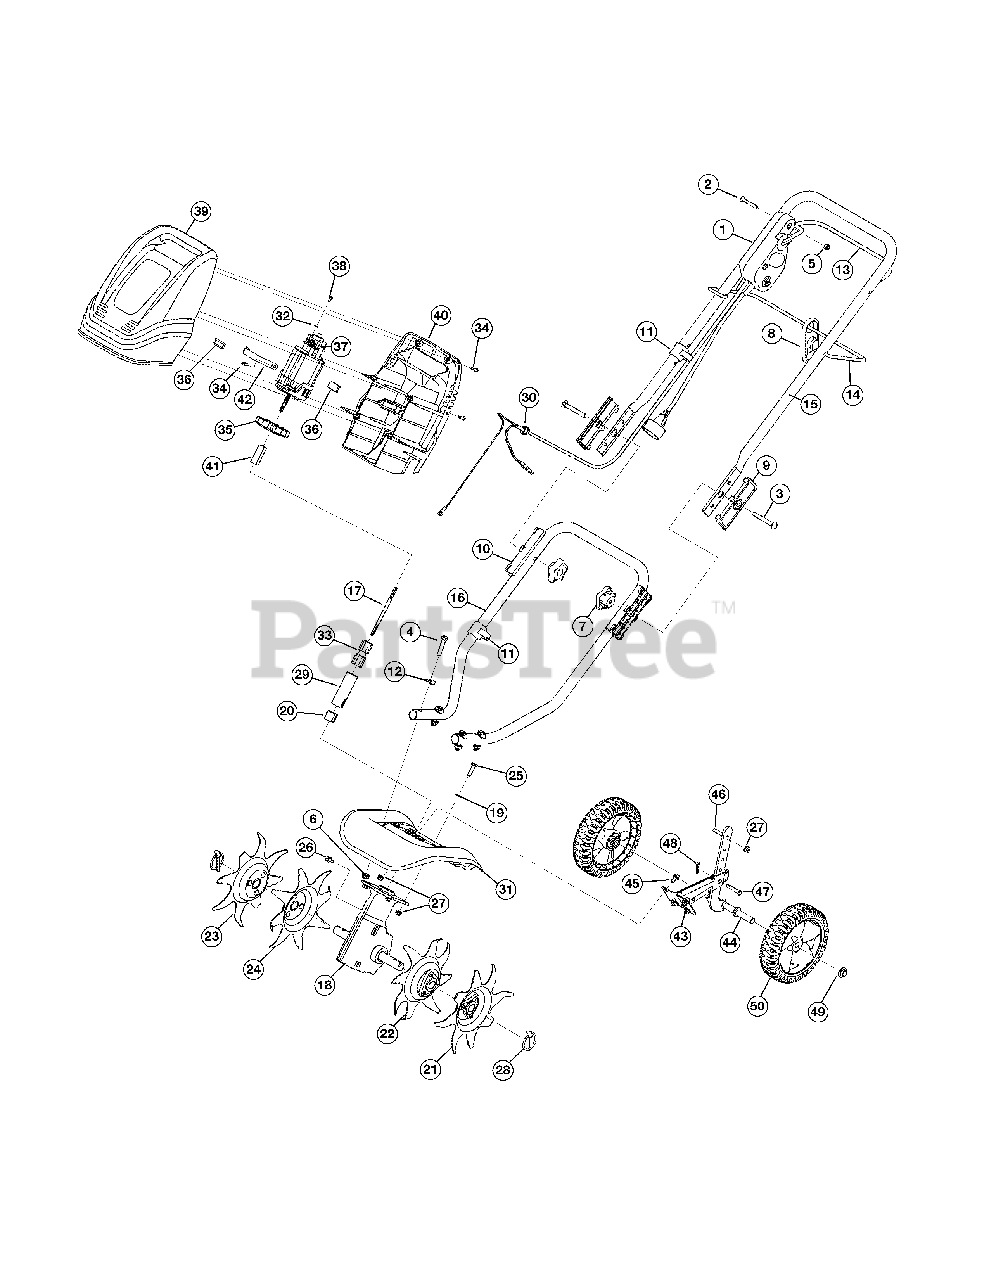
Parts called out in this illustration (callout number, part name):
1	Switch Assembly
4	Screw
8	Cord Retainer
9	Upper Handle Insulator
10	Lower Handle Insulator
11	Cable Guide
12	Saddle Washer
13	Control Bail
15	Upper Handle
16	Lower Handle
17	Flex Shaft
18	Gearbox
19	Washer
20	Sleeve
21	Outer Tine Assembly
22	Inner Tine Assembly
23	Outer Tine Assembly
24	Inner Tine Assembly
25	Screw
26	Bolt
28	Lynch Pin
29	Boom Tube
30	Cord Bushing
31	Tine Shield
32	Lock Washer
33	Flex Tube Assembly
36	Motor Pad
37	Motor Assembly
39	Front Motor Cover
40	Rear Motor Cover
41	Motor Hub
42	Motor Strap
43	Bracket Assembly
44	Wheel Support Bracket Assembly
46	Belt Guard Pin
47	Clevis Pin
48	Cotter Pin
49	Push Cap
50	Wheel (includes 49)
